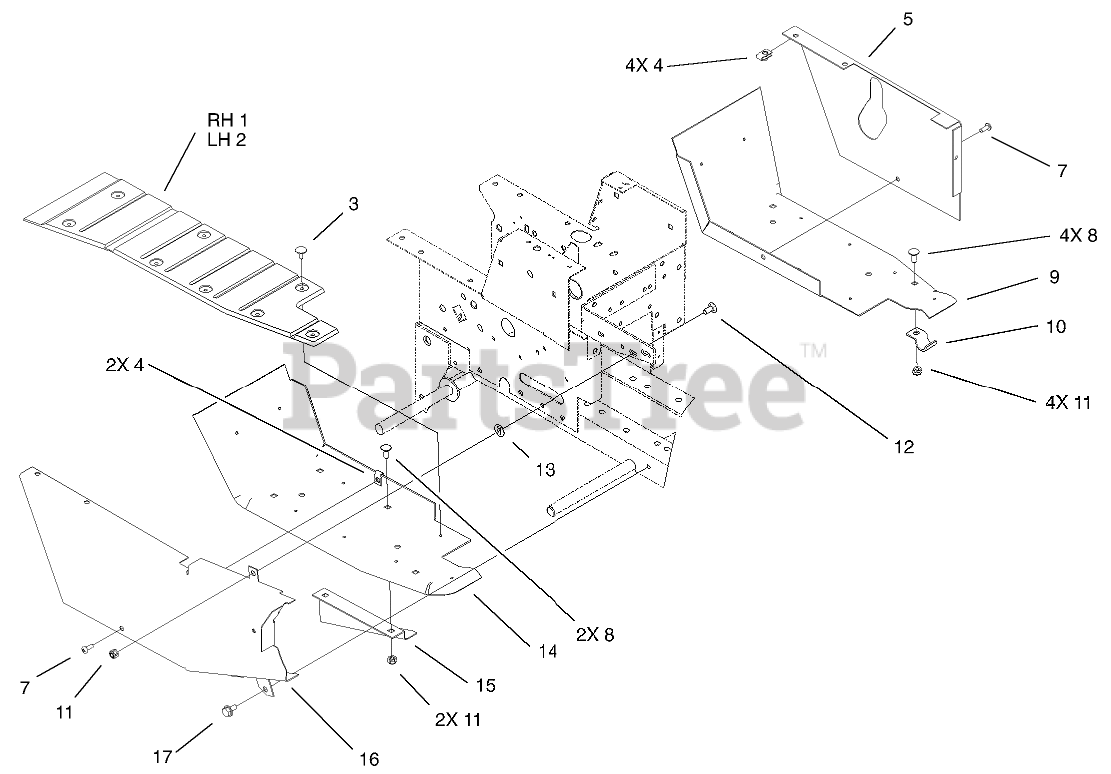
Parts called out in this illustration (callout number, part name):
1	PAD-FOOT RH
2	PAD-FOOT LH
3	FASTENER-PANEL
5	COVER-LH
7	SCREW-PPH
8	BOLT-CARR
9	FOOTREST-LH
10	BRACKET
11	NUT-LOCK, NI
12	BOLT-CARR
13	NUT-PUSH
14	FOOTREST-RH
15	GUIDE-LOWER BELT
16	Belt Guard ASM
17	SCREW-HWHTF
